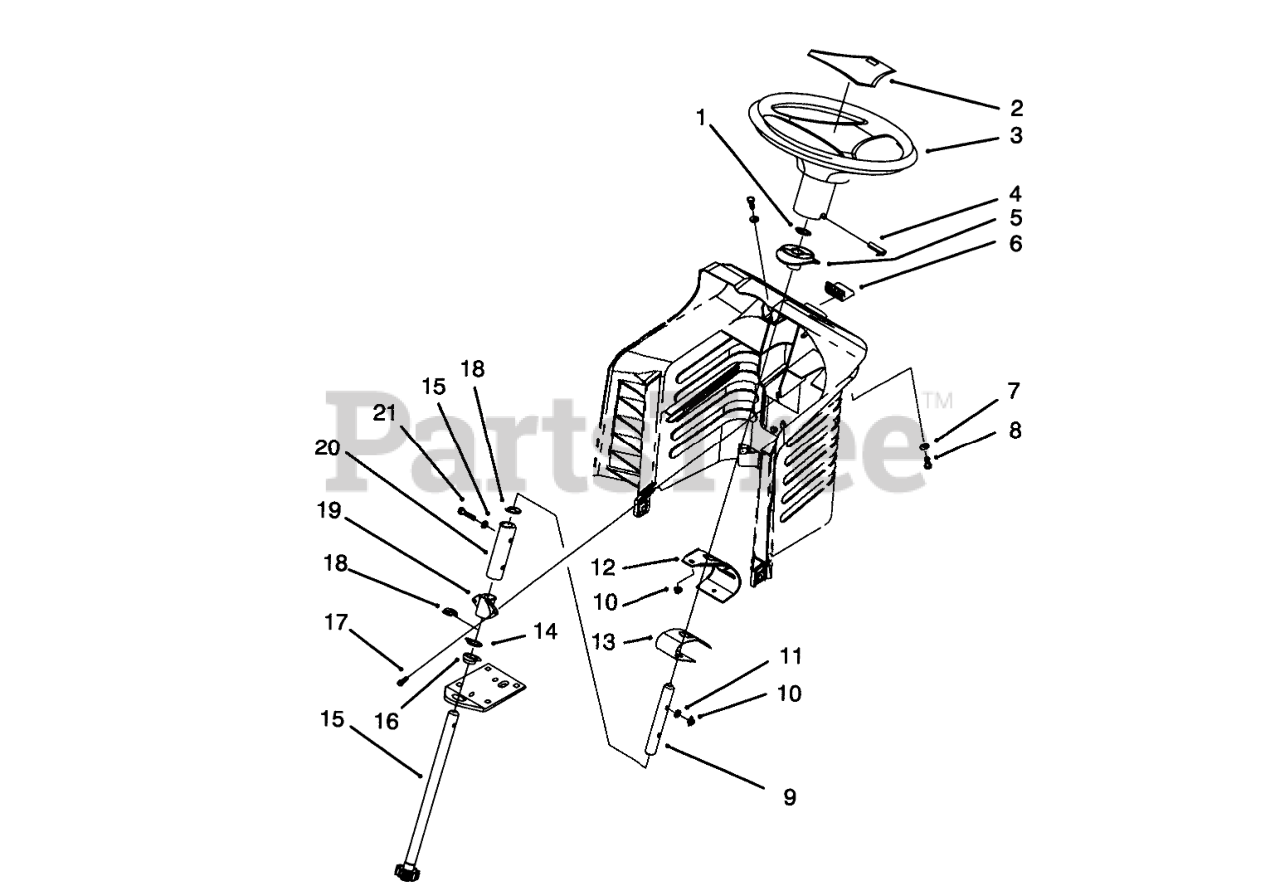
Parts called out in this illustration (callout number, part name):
1	PUSH-ON RETAINING RING
2	COVER-WHEEL
3	Wheel-Steering (Incl. Ref. #2)
4	PIN-ROLL
5	BUSHING-SLIDING
6	RELEASE BUTTON
7	WASHER-FLAT
8	SCREW-HH
9	UPPER STEERING SHAFT
10	NUT-LOCK, NI
11	WASHER
12	BACKUP BRACKET
13	SPRING LEAF
14	WASHER-THRUST
15	SHORT STRG SHAFT WA
16	BEARING-FLANGE
17	SCREW-SPECIAL
18	E-RING
19	BUSHING STATIONARY
20	COUPLING, STEERING
21	SCREW-HH
